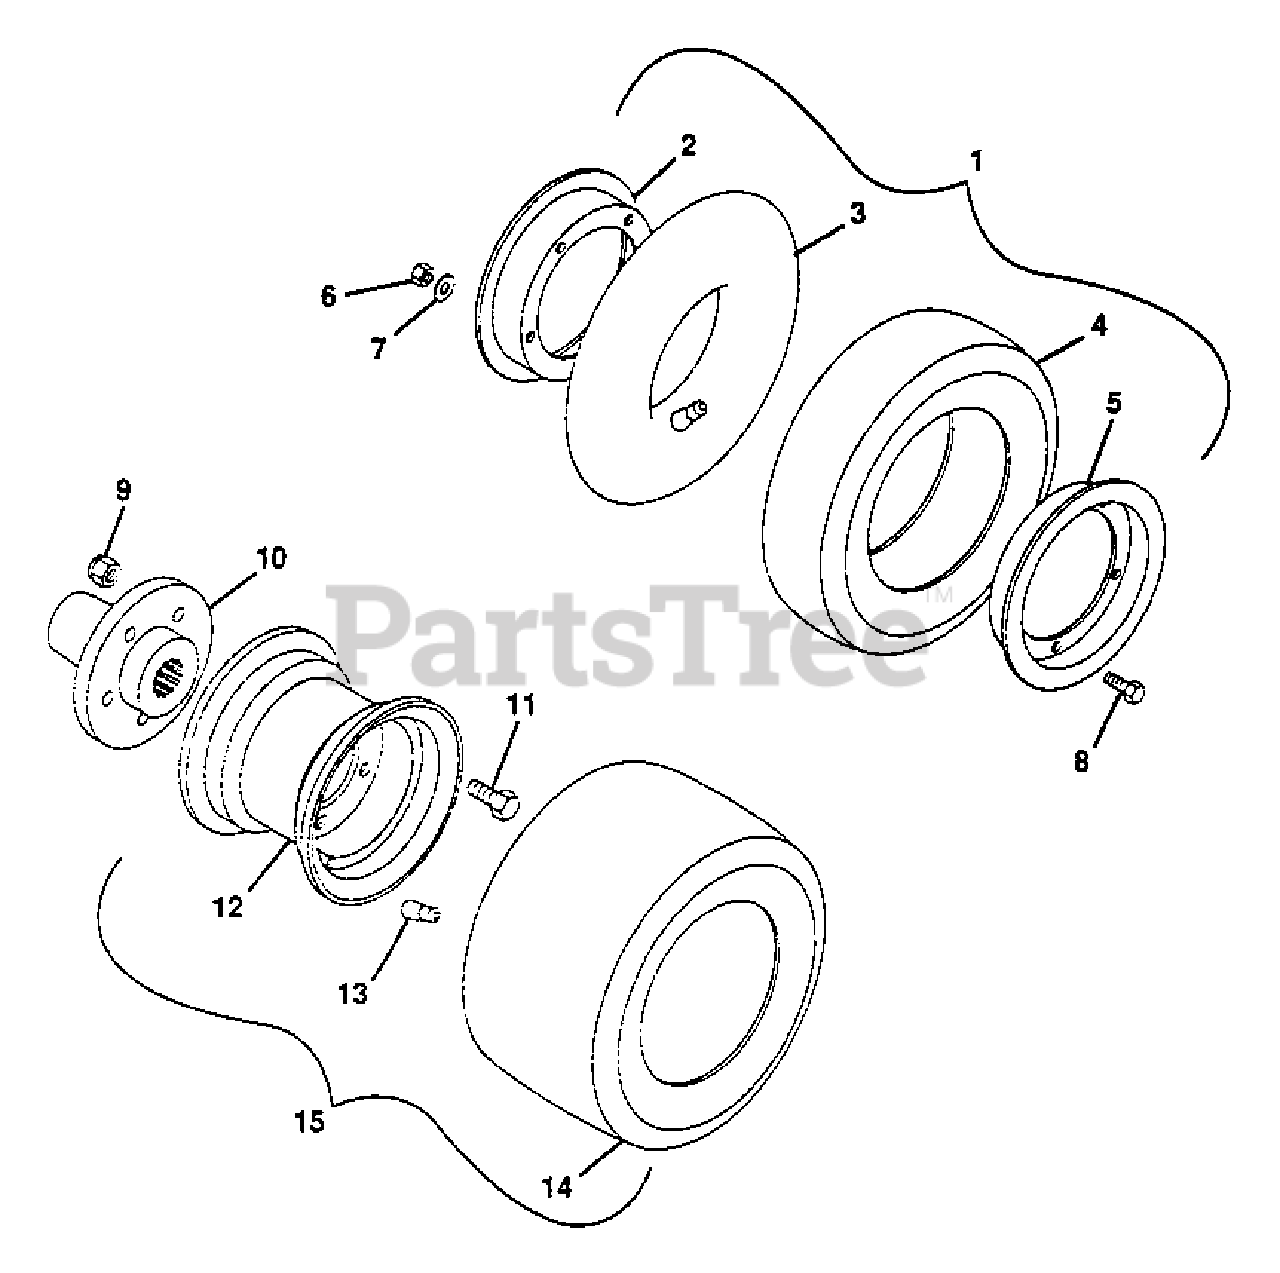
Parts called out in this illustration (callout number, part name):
1	Tire, Ag Type R.H.
1	Asm., D.T. Wheel 4.80x4.00-8
1	Tire, Wheel Asm. 18x6.50-8
1	Wheel, Semi-Pneumatic Asm. 16x5Wx3
1	Asm., Wheel Semi-Pneumatic 19x5
1	Tire, Ag Type L.H.
2	Disc, Inner Wheel
3	Tube, 500x8
3	Tube, Tractor Tire
4	Tire, Tractor D.T. 4.80x4.00-8
4	Tire, Tractor Ground Grip 4.00-8
4	Tire, Semi-Pneumatic 16x5Wx3
4	Tire, 18x6.50-8
4	Tire. 19x5 Semi-Pneumatic
5	Disc, Wheel
6	Nut, Jam 3/8-16 Hex
7	Washer, Lock 3/8 Reg.
8	Bolt, Hex 3/8-16x.625
8	Bolt, Hex 3/8-16x.750
9	Nut, Lock 1/2-13
10	Hub
11	Bolt, Hex 1/2-13x1.50
12	Rim, 18x8.50-8
13	Assembly, Valve Stem
14	Tire, 18x8.50-8
15	Assembly, Wheel 18x8.50x8
